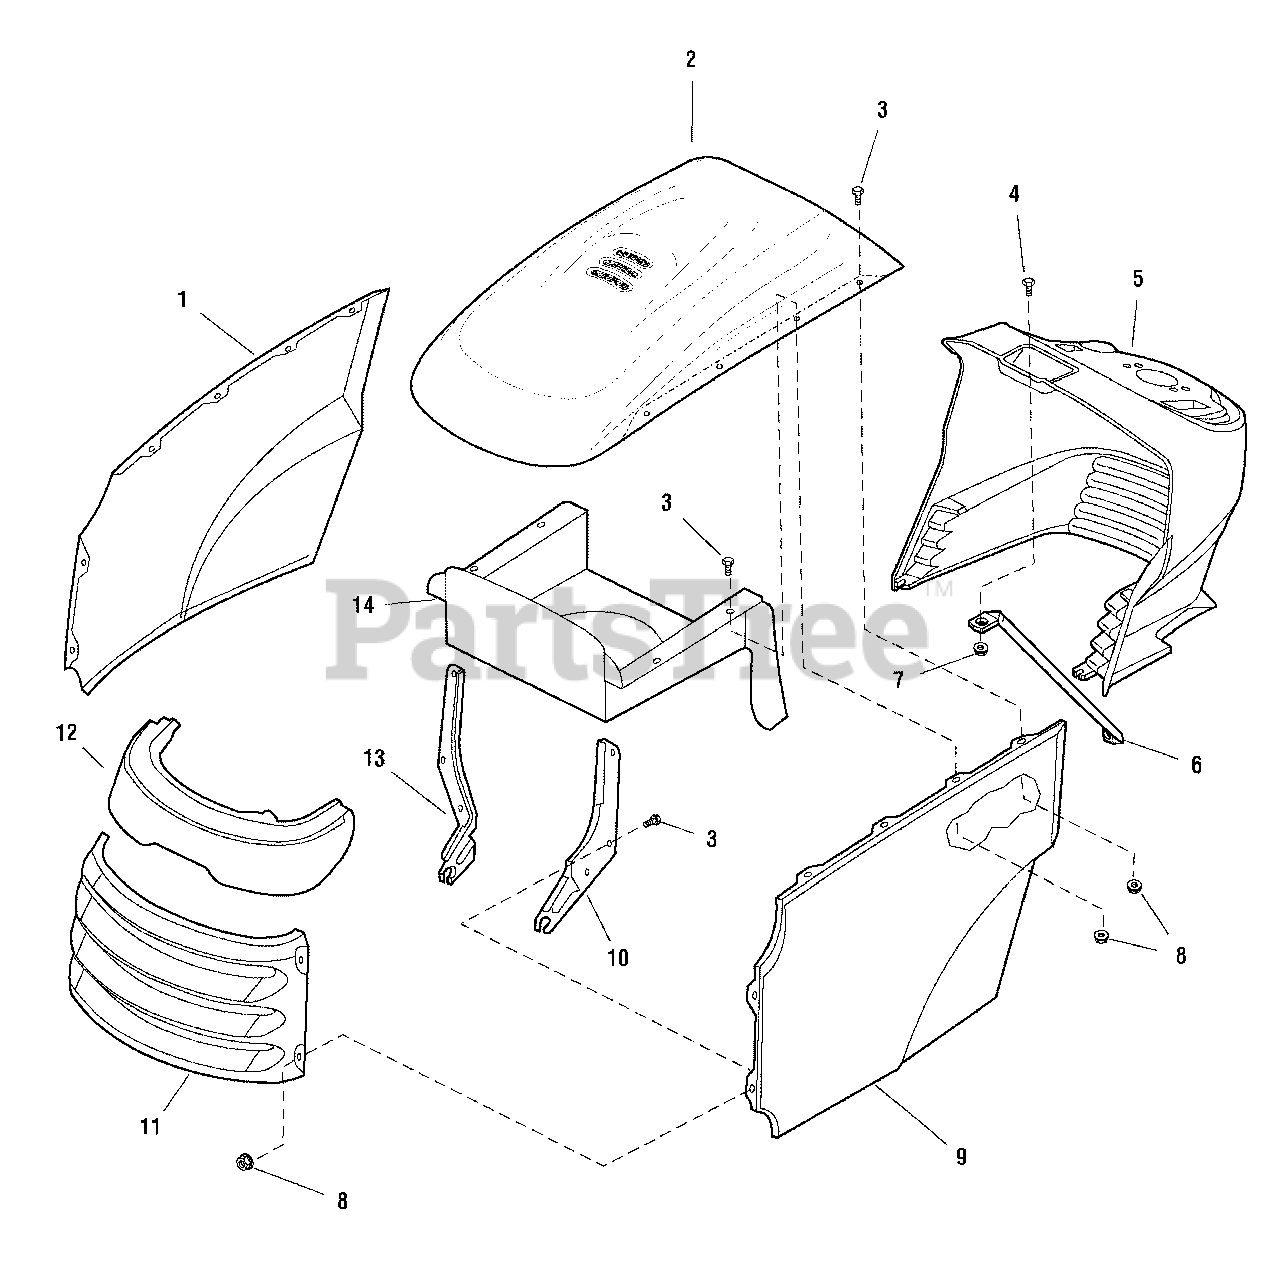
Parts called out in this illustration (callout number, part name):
1	PANEL, RH Side, Orange
1	PANEL, RH Side, Red
2	HOOD, with Louver, Orange
2	HOOD, with Louver, Red
3	CAPSCREW, Hex Flange Whiz Lock, 1/4-20 x 5/8
4	SCREW, Pan Head Phillips, #10-24 x 1
5	DASHBOARD, with Hydro Lift Slot
6	ROD, Dash Support
7	NUT, Hex Lock, with Nylon Insert, 10-24
8	NUT, Hex Flange Whiz Lock Large, 1/4-20 Black
9	PANEL, LH Side, Orange
9	PANEL, LH Side, Red
11	GRILLE, Orange
11	GRILLE, Red
12	HEADLIGHT ASSEMBLY, 4 Bulb
14	DUCT, Air Inlet 18GA
